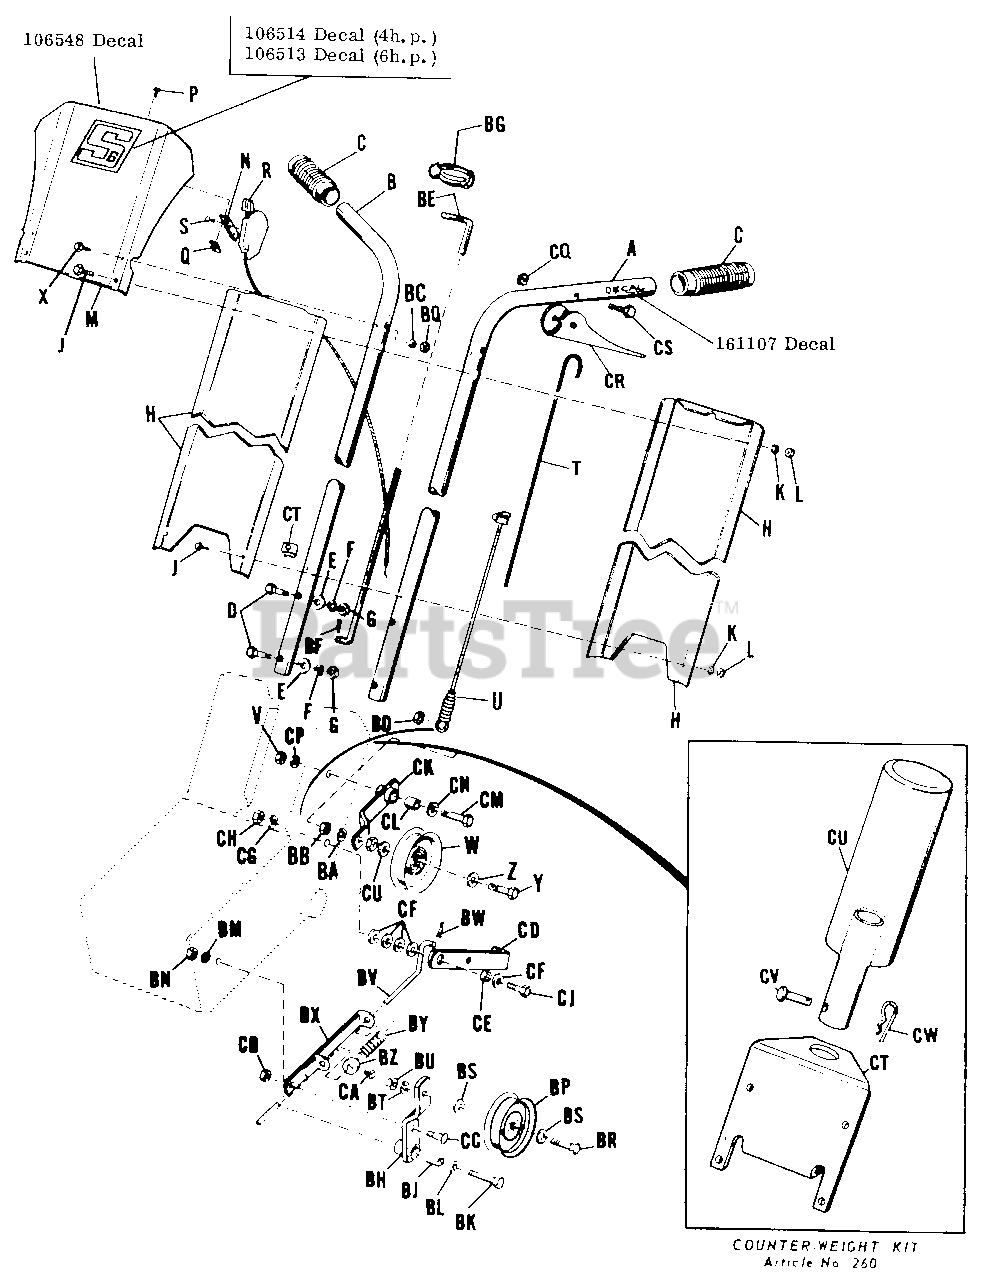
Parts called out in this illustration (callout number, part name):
A	Handle, LH
B	Handle, RH
D	Hex Capscrew, 3/8"-16 x 2"
E	Washer, Plain, 3/8"
F	Lock Washer, 3/8"
G	Hex Nut, Full, 3/8"-16
H	Handle Cover
J	Hex Capscrew, 1/4-20 x 1-1/2
K	LockWasher, 1/4"
L	Hex Nut, Full 1/4"-20
M	Housing Assembly
N	Support, Throttle Control
P	Hex Screw, self-tap. #10-32 x 1/2
Q	Speed Nut, Tinnerman
R	Throttle Control Assembly
S	Screw, Self-Tap. #10-24 x 1/2
T	Extension Spring
U	Spring Assy.
V	Hex Nut, Full, 3/8"-16
W	Idler Pulley (Trans. Drive)
X	Hex Capscrew, 1/4-20 x 1-3/4
Y	Hex Capscrew, 3/8"-16 x 2"
Z	Plain Washer, 3/8"
BA	Lock Washer, 3/8"
BB	Hex Nut, Full, 3/8"-16
BC	Lock Washer, 1/4"
BD	Hex Nut, Full, Lock, 3/8"-16
BE	Reverse Rod
BF	Cotter Pin, 3/32" x 3/4"
BG	Grip, Reverse Rod
BH	Idler Lever Assembly
BJ	Bearing Race, Inner
BK	Hex Capserew, 3/8-16 x 1-3/4
BL	Plain Washer, 3/8"
BM	Lock Washer, 3/8"
BN	Hex Nut, Full, 3/8"-16
BP	Idler Pulley (Rotor Drive)
BQ	Hex Nut, Full, 1/4"-20
BR	Hex Capserew, 3/8-16 x 1-3/4
BS	Plain Washer, 3/8"
BT	Lock Washer, 3/8"
BU	Hex Nut, Full, 3/8"-16
BV	Rotor Clutch Rod
BW	Cotter Pin, 3/32" x 3/4" lg.
BX	Clutch Rod Guide Assembly
CA	Set Screw, Sq. Hd. 1/4-20 x 3/8
CB	Hex Nut Full, Lock, 3/8"-16
CC	Hex Capserew, 3/8"-16 x 3/4
CD	Foot Clutch Pedal
CF	Plain Washer, 3/8"
CG	Lock Washer, 3/8"
CH	Hex Nut, Full, 3/8"-16
CJ	Hex Capserew, 3/8-16 x 1-1/2
CK	Idler Lever Assembly
CL	Race, Inner Bearing
CM	Hex Capscrew, 3/8-16 x 1-3/4
CN	Plain Washer, 3/8"
CP	Lock Washer, 3/8"
CQ	Hex Nut, Full, Lock, 1/4-20
CR	Clutch Grip
CS	Hex Capscrew, 1/4-20 x 1-1/2
